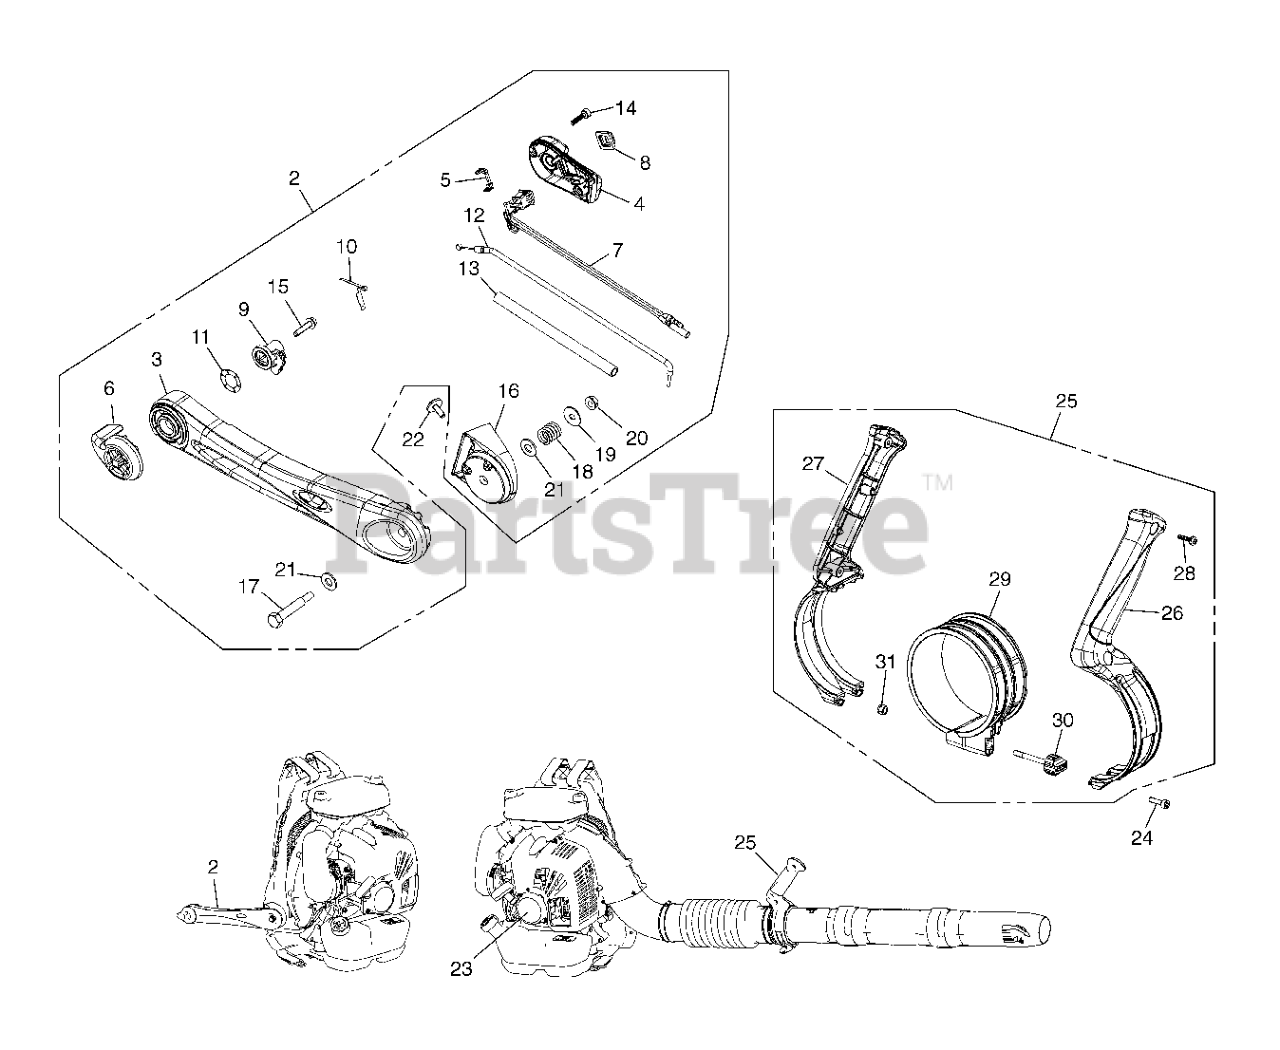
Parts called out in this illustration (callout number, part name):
2	LEVER,SET
6	LEVER,THROTTLE
8	CAP SWITCH
10	PLATE, CONTACT
11	WASHER WAVE
15	BOLT
19	WASHER Z349525440
20	NUT 8488646000
23	RECOIL DECAL
25	GRIP ASSY
26	GRIP,RIGHT
27	GRIP,LEFT
